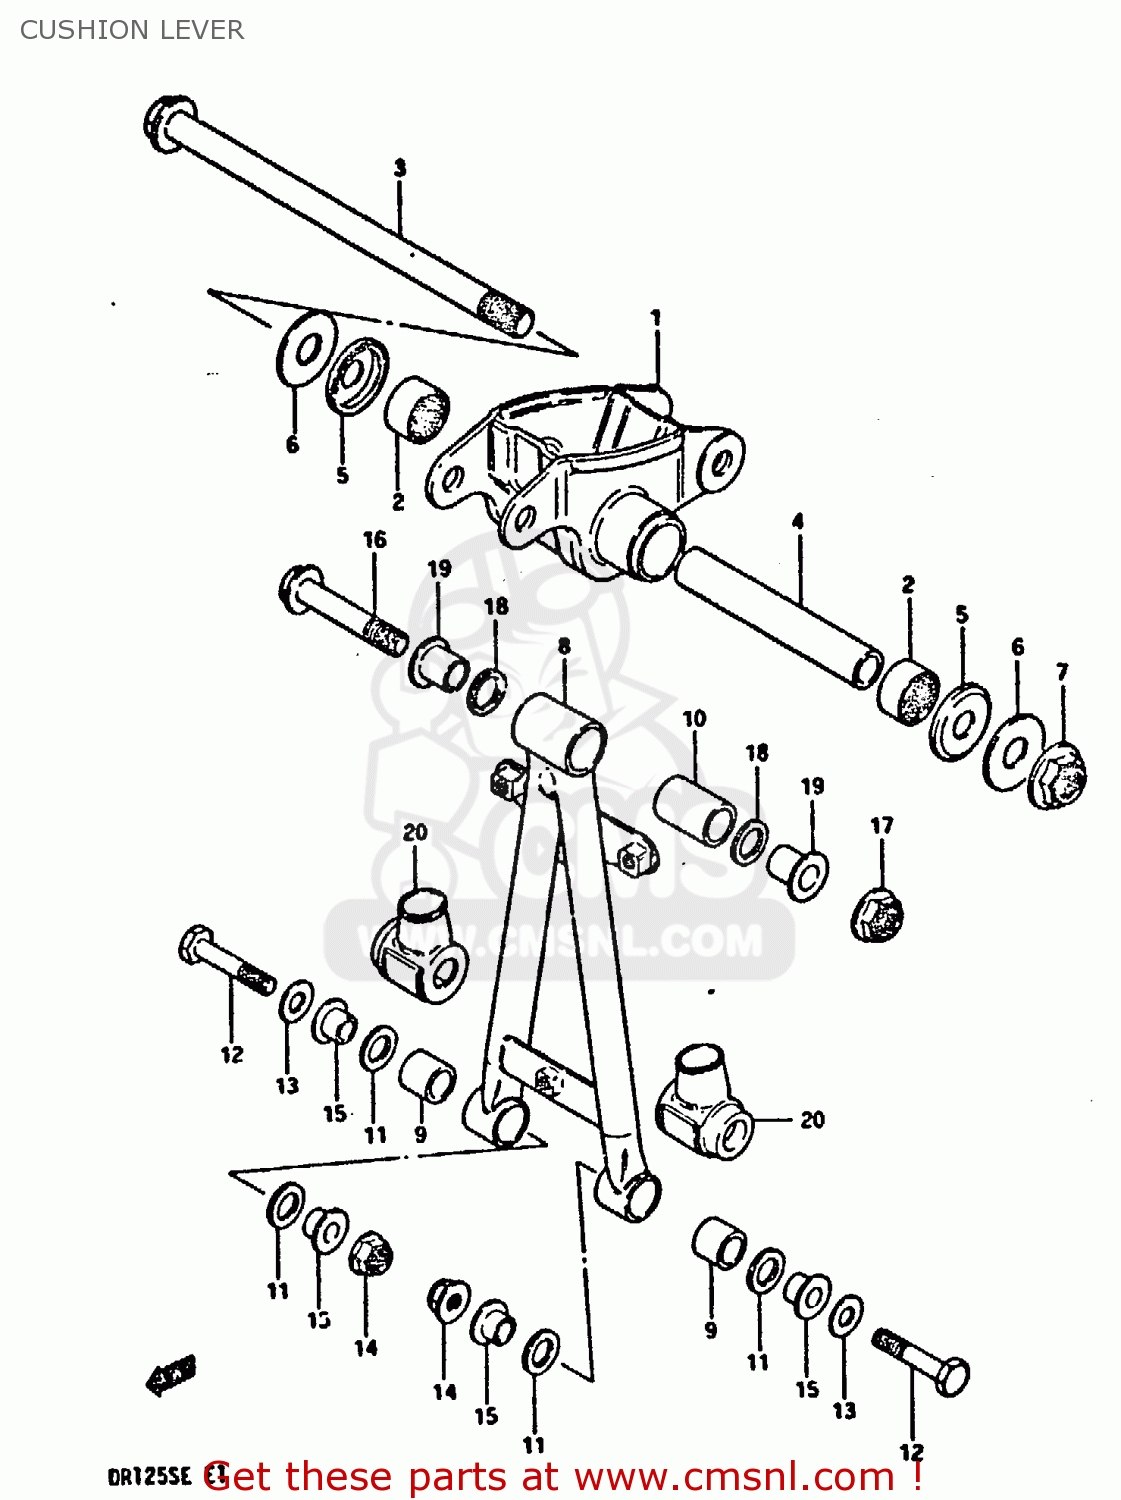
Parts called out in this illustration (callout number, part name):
1	LEVER ASSEMBLY,REAR CUSHION
2	BEARING(17X25X20)
3	SHAFT,REAR CUSHION LEVER
4	SPACER
5	DUST SEAL,RR CUSHION LEVER
6	WASHER
7	NUT 12MM
8	ROD SET,REAR CUSHION LEVER
9	BUSHING
10	BUSH,UPPER
11	DUST SEAL,RR CUSHION LOD LWR
12	BOLT,REAR CUSHION ROD
13	WASHER
14	NUT
15	SPACER,RR CUSHION ROD LWR
16	BOLT(10X65)
17	NUT
18	DUST SEAL,LEVER CUSHION UNIT
19	SPACER,RR CUSHION ROD UPR
20	BOOT,REAR CUSHION ROD,LOWER
